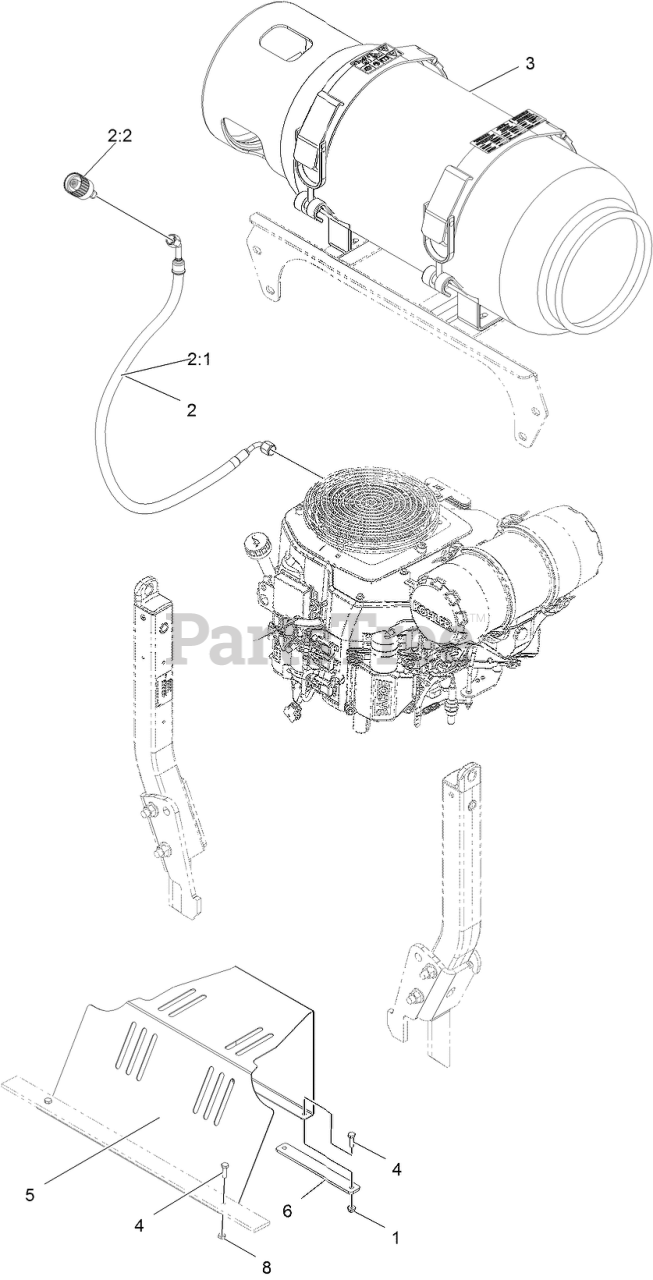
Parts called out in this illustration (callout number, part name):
2	LPG HOSE ASM
2:1	HOSE ASM, LPG
2:2	CONNECTOR-LP, STRAIGHT
3	TANK-LPG
4	SCREW-HH
5	SHEILD-FAN
8	NUT-JAM
